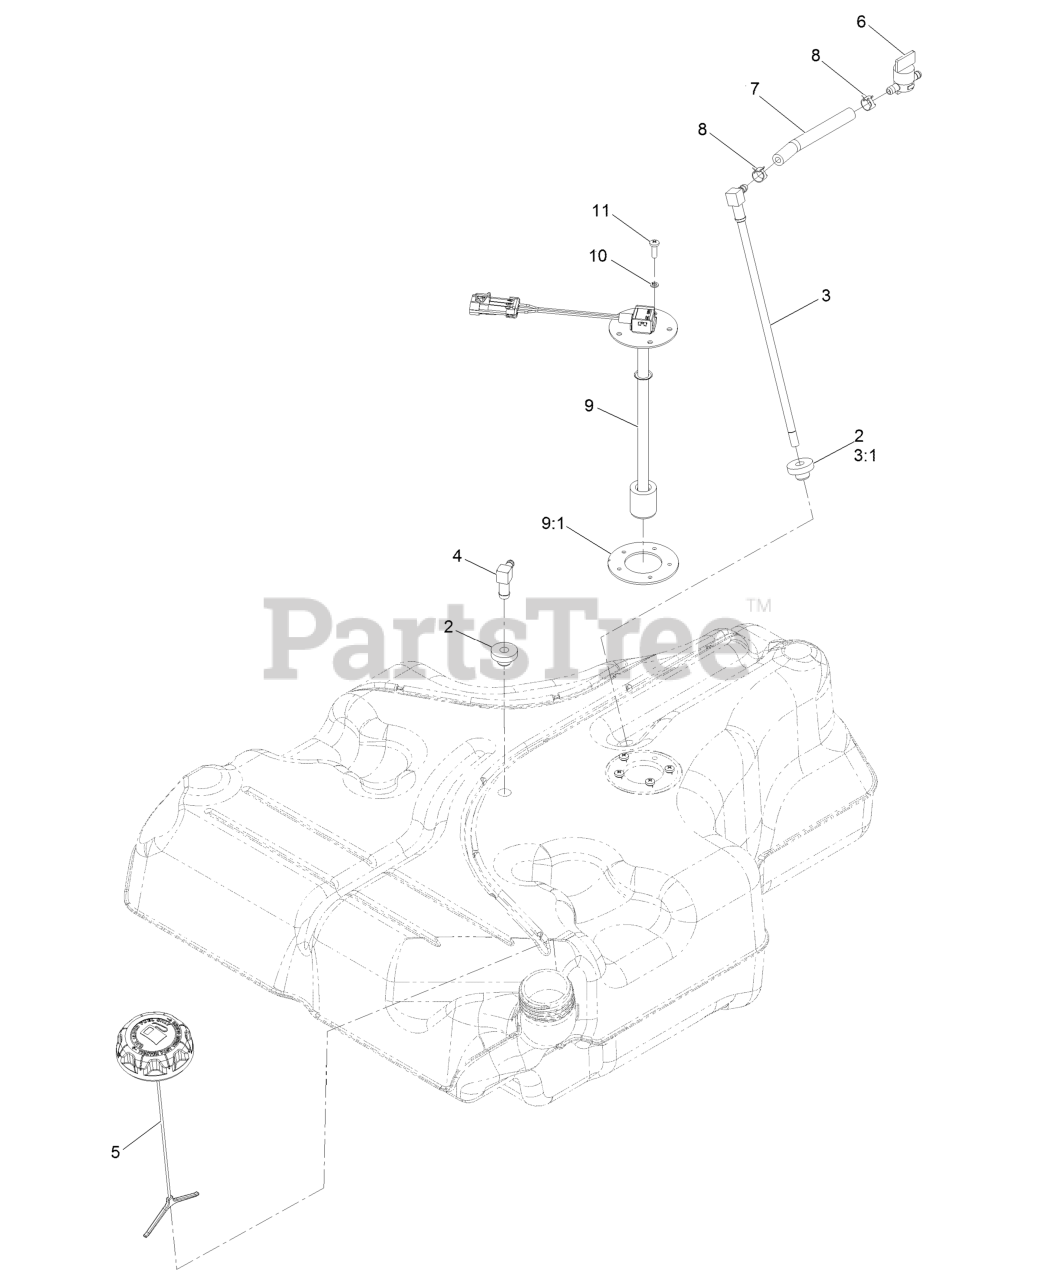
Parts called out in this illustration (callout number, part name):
2	Bushing
3	Fuel Line Kit (With Grommet)
3:1	Bushing
4	Fitting-90 Elbow
5	Cap-Fuel, Ratcheting
6	Valve-Fuel
7	Hose-Fuel
8	Clamp-Hose
9	Sender-Level, Fuel (W/Gasket)
9:1	Gasket-Sender
10	Washer-Lock 3/16
11	Screw-PPH #10-24 X 5/8
